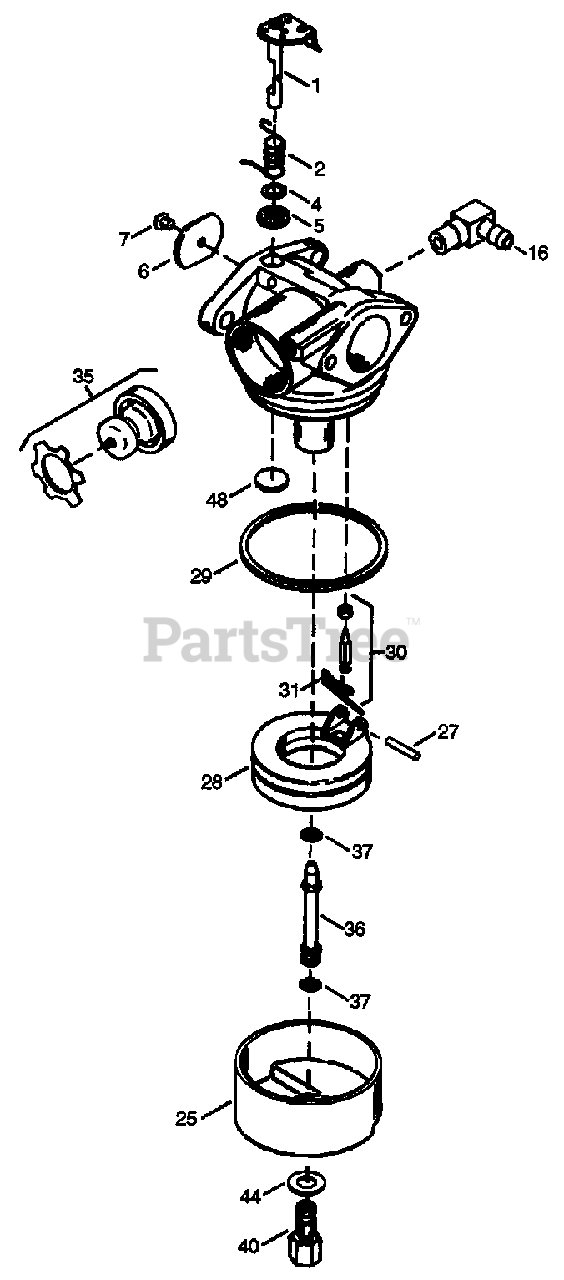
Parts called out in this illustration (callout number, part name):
1	Throttle Shaft & Lever Assembly
2	Throttle Return Spring
4	Dust Seal Washer
5	Dust Seal (Throttle)
6	Throttle Shutter
7	Shutter Screw
16	Fuel Fitting
25	Float Bowl
27	Float Shaft
29	Float Bowl "O" Ring
30	Inlet Needle, Seat, & Clip (Incl. 31)
31	Spring Clip
35	Primer Bulb/Retainer Ring
36	Main Nozzle Tube
37	O-Ring, Main Nozzle Tube
40	High Speed Bowl Nut
44	Bowl Nut Washer
48	Welch Plug, Atmospheric Vent
